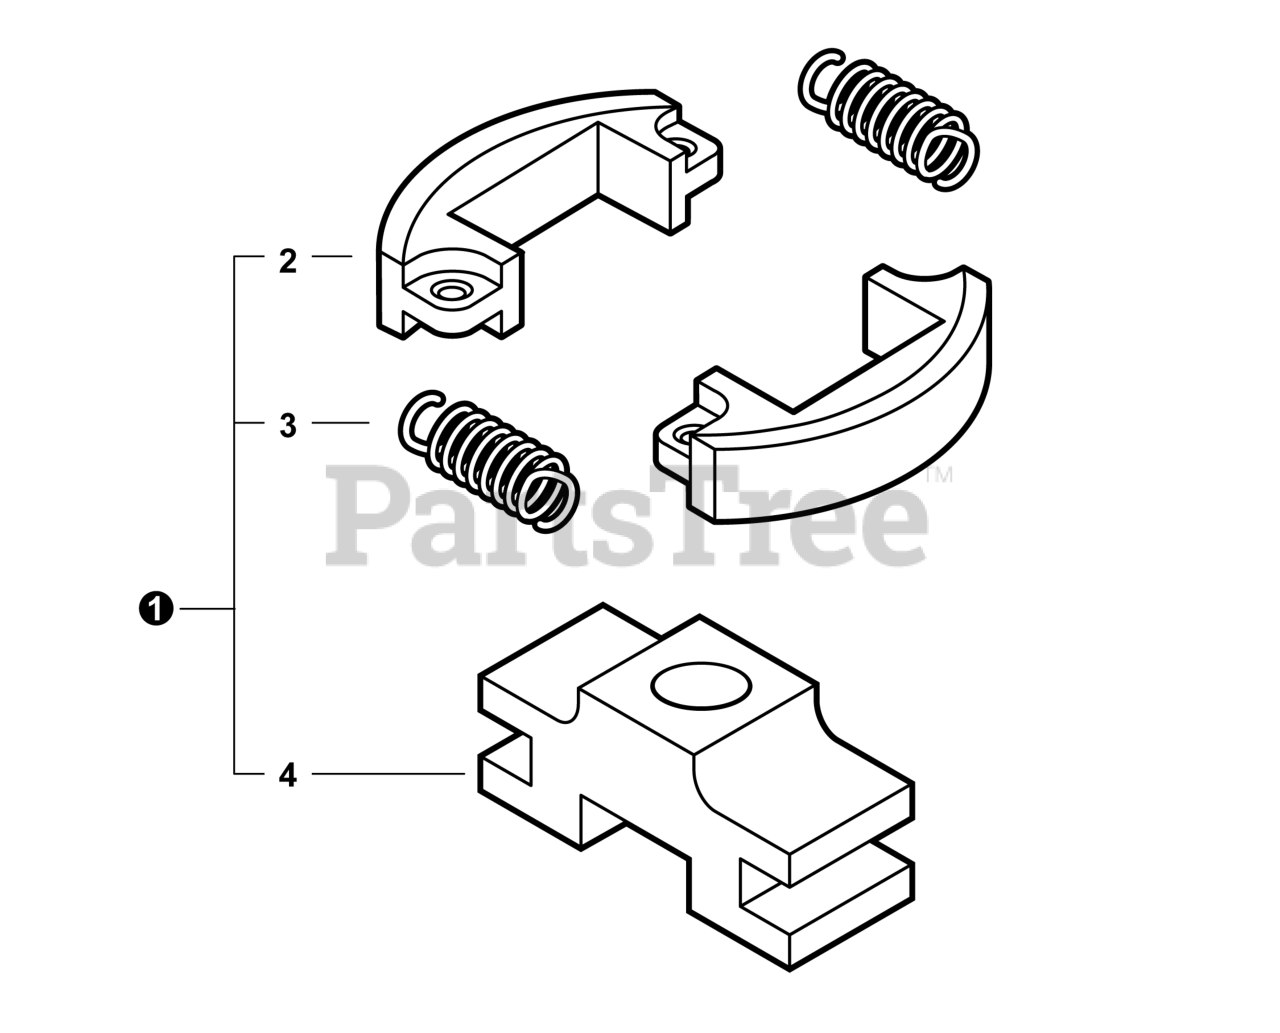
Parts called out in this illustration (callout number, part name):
1	CLUTCH ASSY
2	SHOE, CLUTCH
3	SPRING, CLUTCH
4	HUB, CLUTCH
